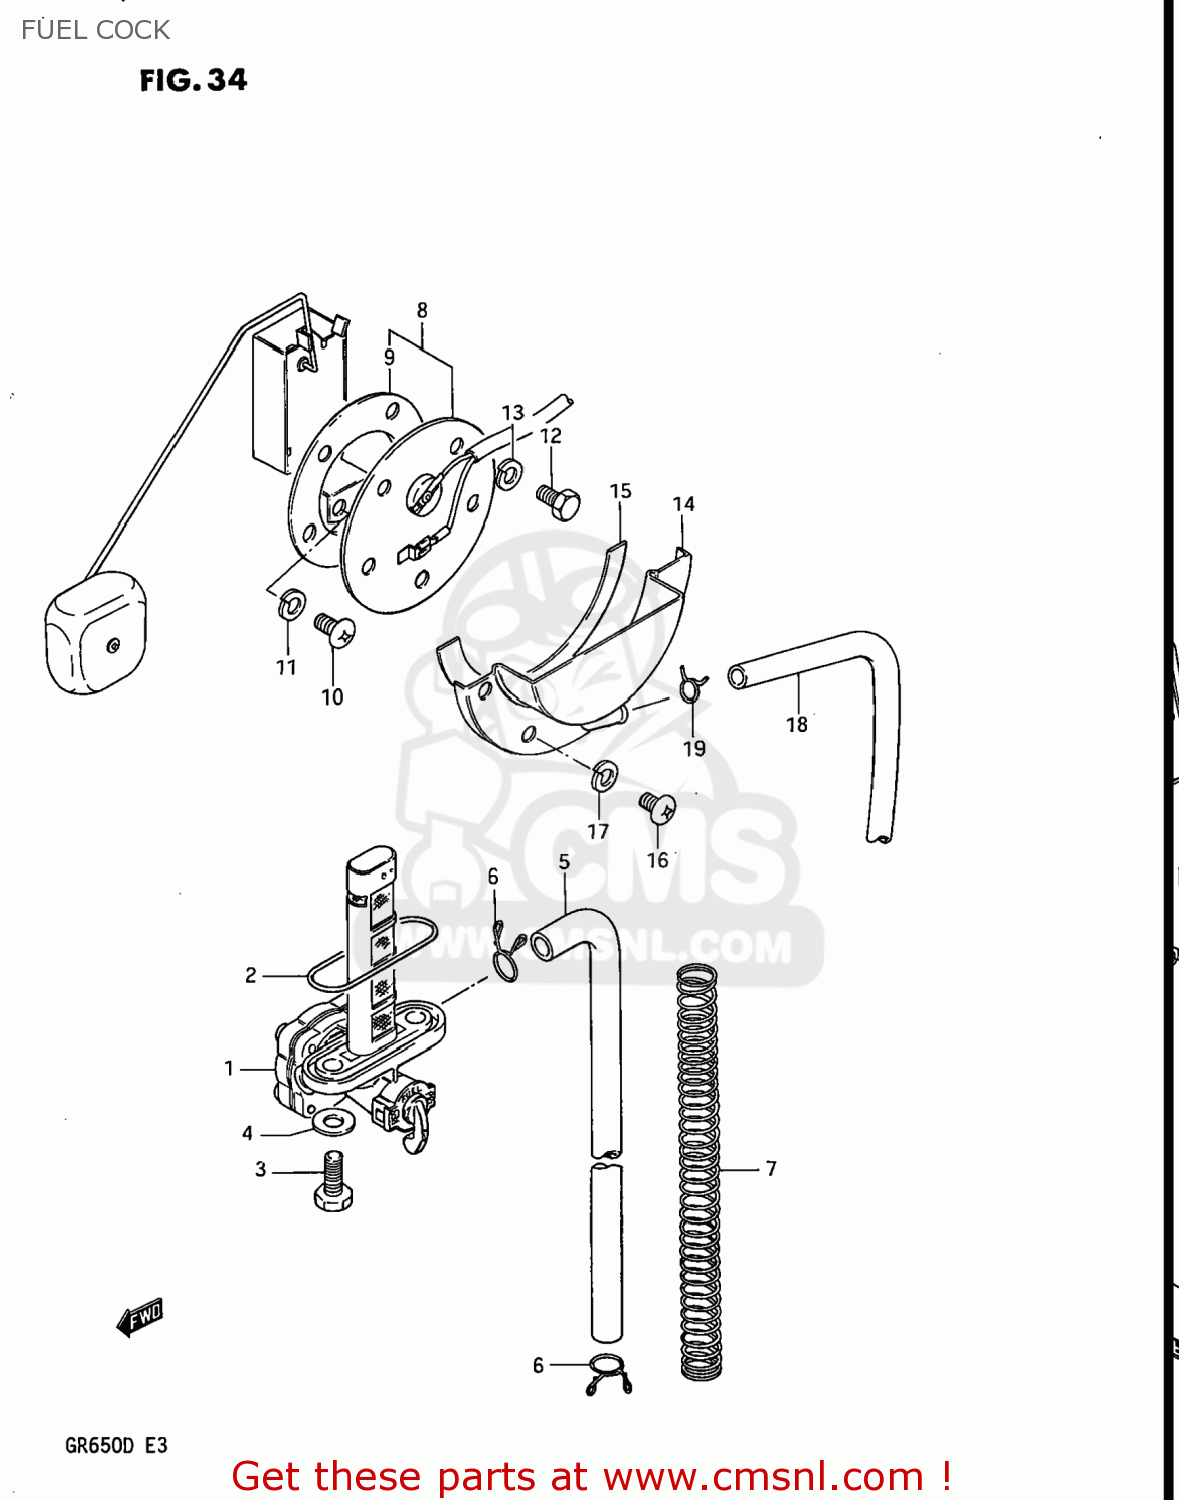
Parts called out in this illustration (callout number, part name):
1	COCK ASSEMBLY,FUEL
2	O RING
3	BOLT(6X20)
4	GASKET
5	HOSE
6	CLIP
7	SPRING
8	GAUGE ASSEMBLY,FUEL LEVEL
9	GASKET,FUEL LEVEL GAUGE (NAS)
10	SCREW
11	LOCK WASHER
12	BOLT
13	LOCK WASHER
14	PLATE,FUEL DRAIN
15	GASKET (NAS)
16	SCREW
17	LOCK WASHER
18	HOSE,FUEL
19	CLIP
